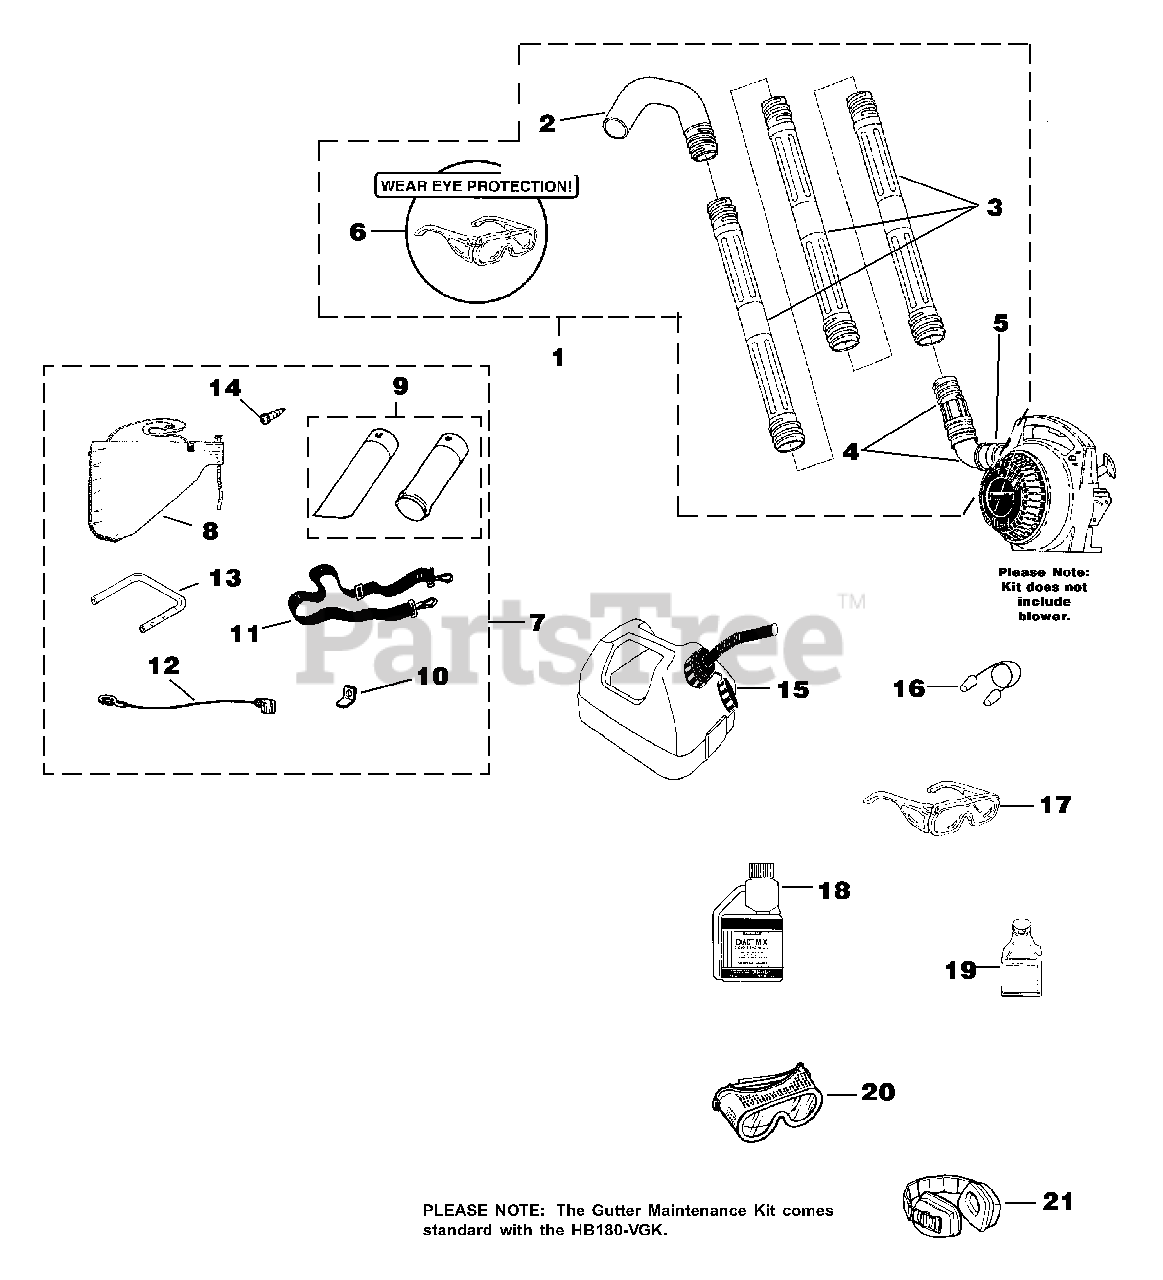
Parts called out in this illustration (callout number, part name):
1	GUTTER MAINTENANCE KIT
2	FULL ELBOW
3	STRAIGHT TUBE
4	UPPER ELBOW & SWIVEL ADAPTER
5	CLAMP w/Fasteners
6	SAFETY GLASSES-Clear
7	VACUUM KIT
8	LEAF BAG
9	VACUUM TUBE KIT w/ Decal
10	TAB-Male
11	HARNESS-Shoulder
12	LEAD-Ground
13	HANDLE
14	SCREW
15	GAS CAN 1 1/4 Gallon
16	EAR PLUGS
17	SAFETY GLASSES-Clear
18	EXACT MIX(TM) Oil - 1 pint (50:1)
19	EXACT MIX(TM) Oil - 2.6 oz. (50:1)
21	EAR PROTECTORS
